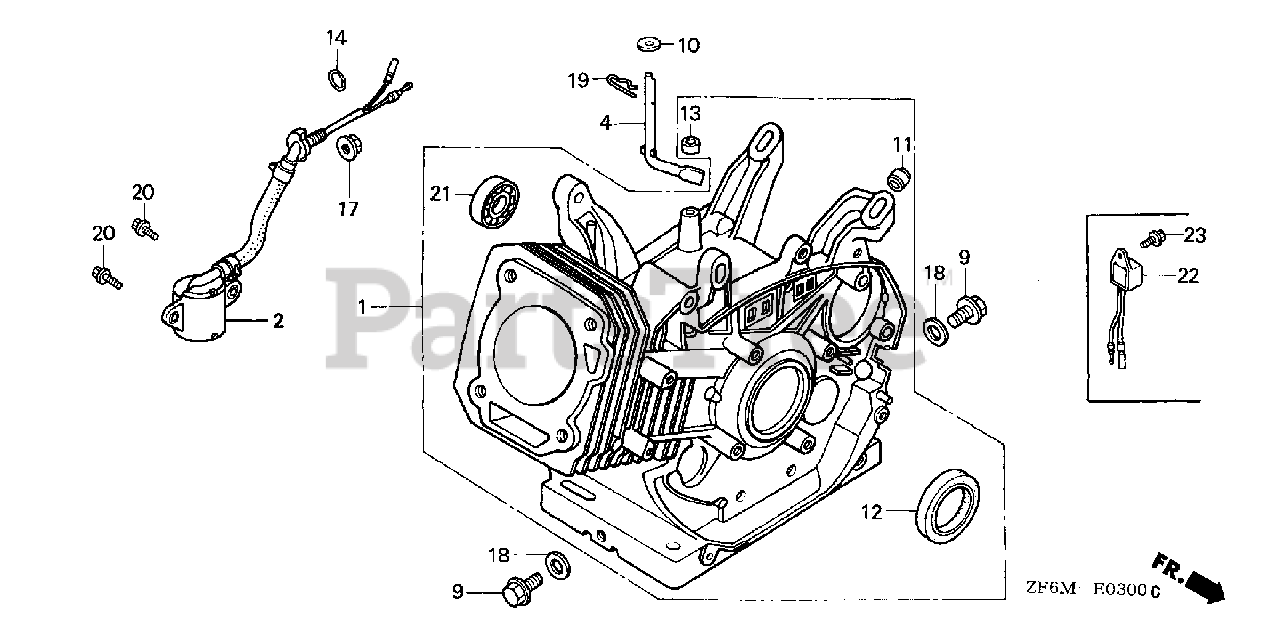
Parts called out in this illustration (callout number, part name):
1	CYLINDER ASSY. (ALERT)
2	SWITCH ASSY., OIL LEVEL
4	SHAFT, GOVERNOR ARM
9	BOLT, DRAIN PLUG
10	WASHER (8.2X17X0.8)
12	OIL SEAL (35X52X8)
13	OIL SEAL (8X14X5)
14	O-RING (13.5X1.5) (ARAI)
17	NUT, FLANGE (10MM)
18	WASHER, DRAIN PLUG (12MM)
19	PIN, LOCK (10MM)
20	BOLT, FLANGE (6X12)
21	BEARING, RADIAL BALL (6202)
22	ALERT UNIT, OIL
23	BOLT, FLANGE (6X12) (CT200)
